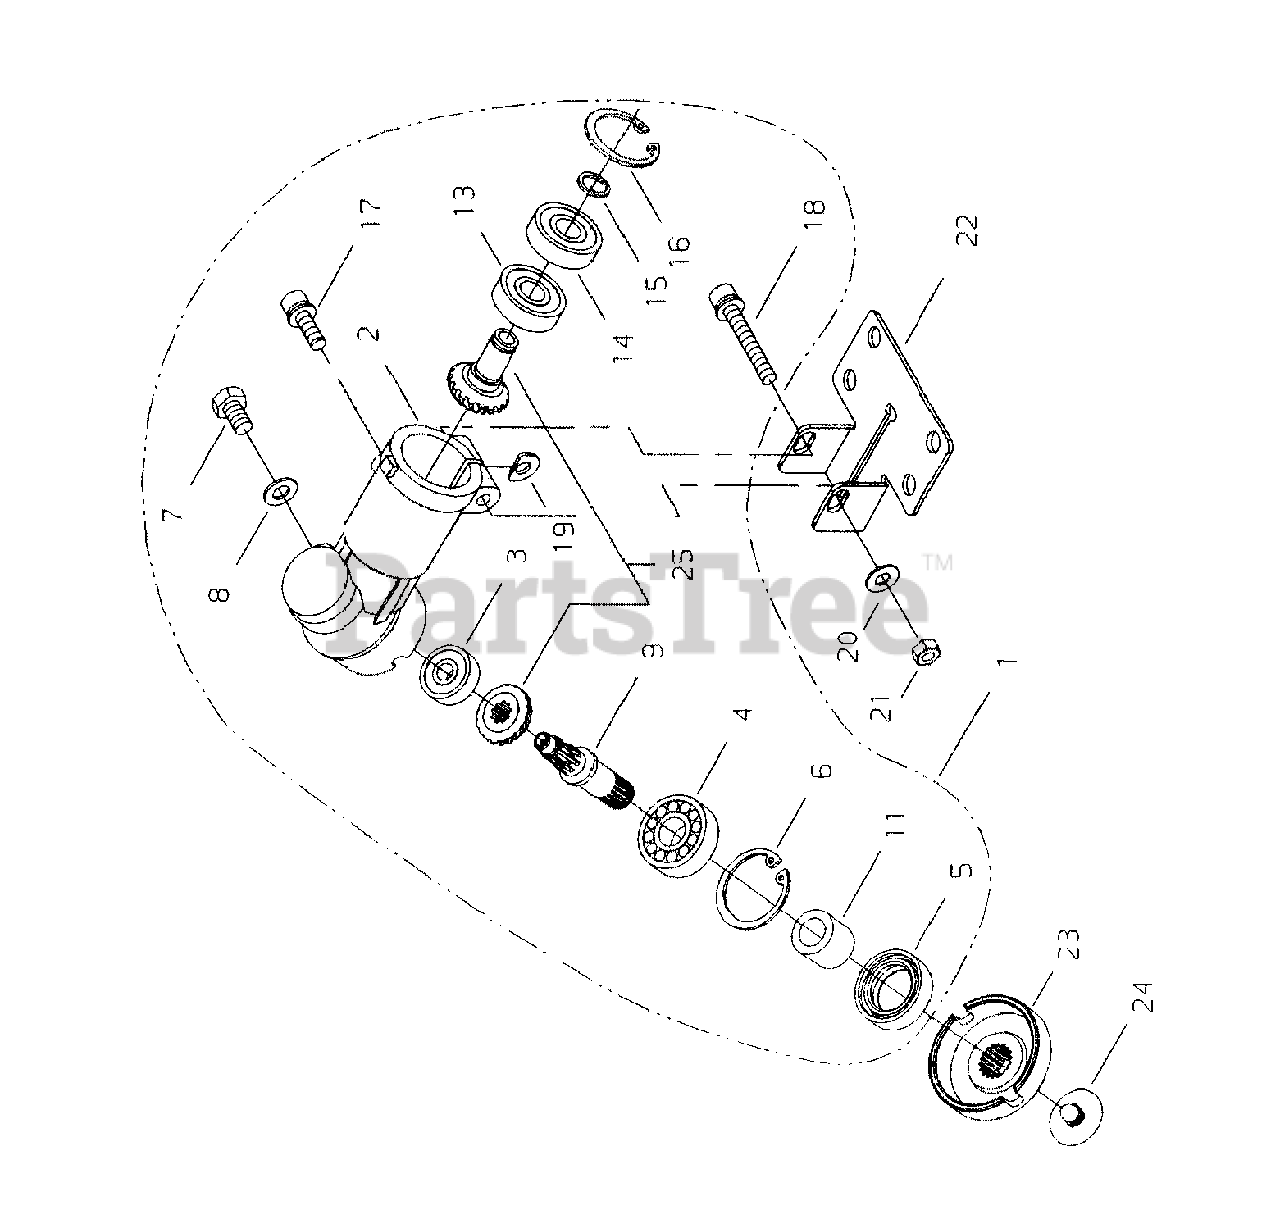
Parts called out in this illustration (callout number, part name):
1	GEAR CASE ASSY
2	CASE, GEAR
3	BEARING, BALL - 608DDU
4	BEARING, BALL - 6001
5	SEAL, OIL
6	RING, RETAINING - 28
7	BOLT - 6X10
8	WASHER - 6
9	GEAR - SHAFT
11	SPACER
13	BEARING, BALL - 609
14	BEARING, BALL 609ZZ
15	RING, RETAINING - 10
16	RING, RETAINING - 24
17	SCREW - 5X16
18	SCREW - 5X35
19	SHIM
20	WASHER - 5
21	NUT - 5
22	PLATE, SHIELD MOUNTING
23	ADAPTOR, BLADE - UPPER
24	ADAPTOR, BLADE - LOWER
25	GUARD
26	BOLT - 8 -- LEFT HAND
27	CLIP
28	GEAR SET
